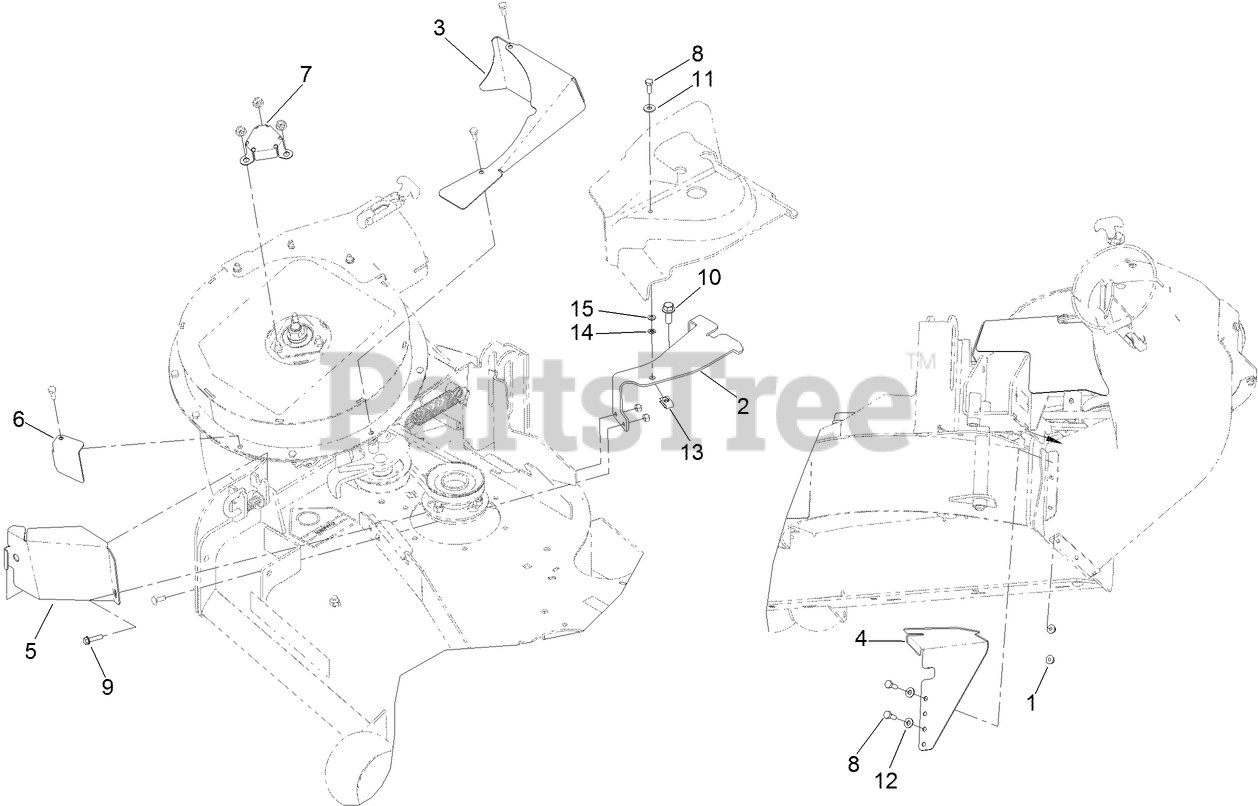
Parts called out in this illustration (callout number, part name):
1	NUT-HF
2	BRACKET-COVER
3	GUARD-TOP
4	GUARD-BAGGER
5	GUARD-BAGGER
6	GUARD-LEFT
7	COVER-NUT
8	SCREW-HH
9	SCREW-HHF
10	SCREW-HHF
11	WASHER-FLAT
12	WASHER-FLAT
14	NUT-RETAINER
15	WASHER-FLAT
